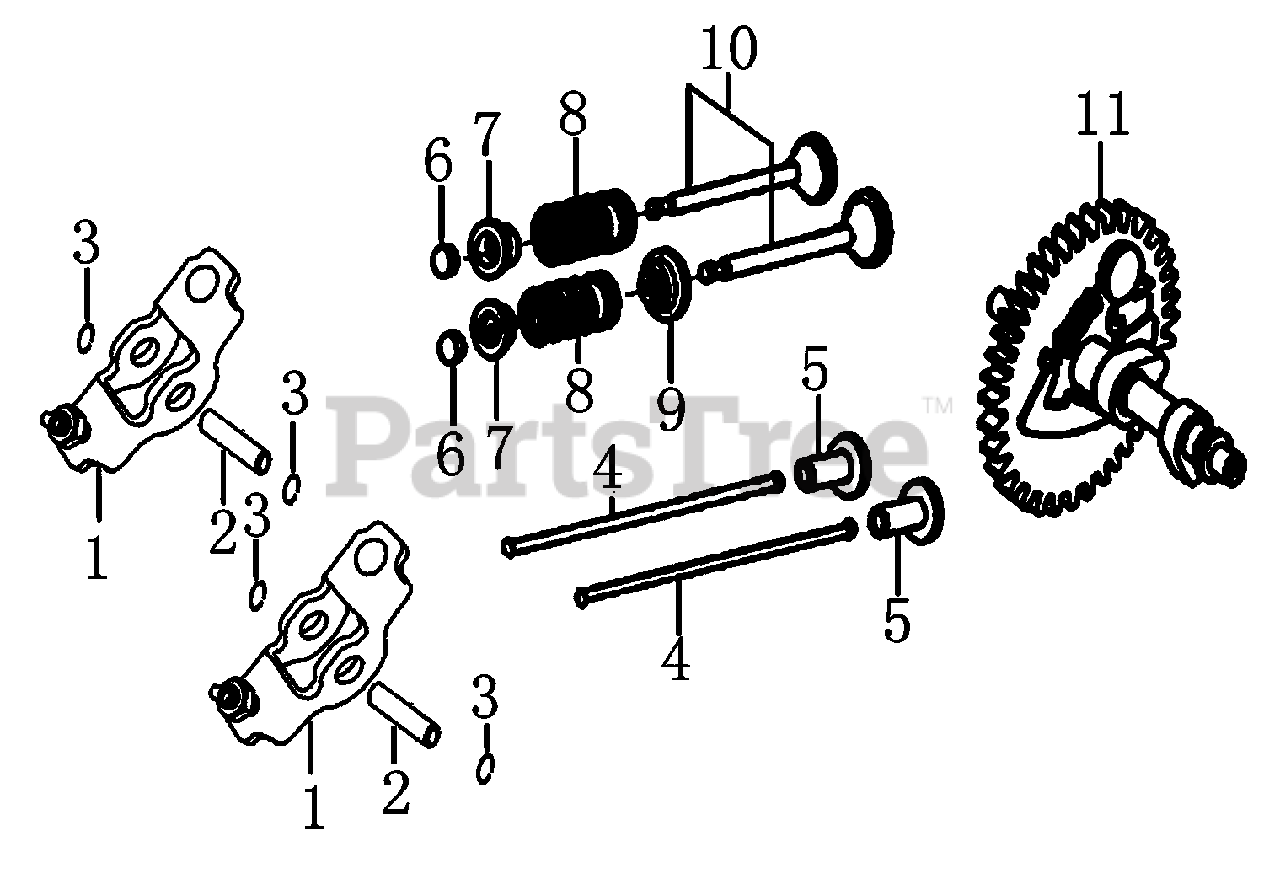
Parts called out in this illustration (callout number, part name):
1	ARM, ROCKER
2	SHAFT, ROCKER VALVE
4	ROD, PUSH
5	LIFTER, VALVE
6	ROTATOR, VALVE
7	RETAINER, VALVE SPRING
8	SPRING, VALVE
9	SEAL, GUIDE
10	VALVE COMP.
11	CAMSHAFT ASSY.
